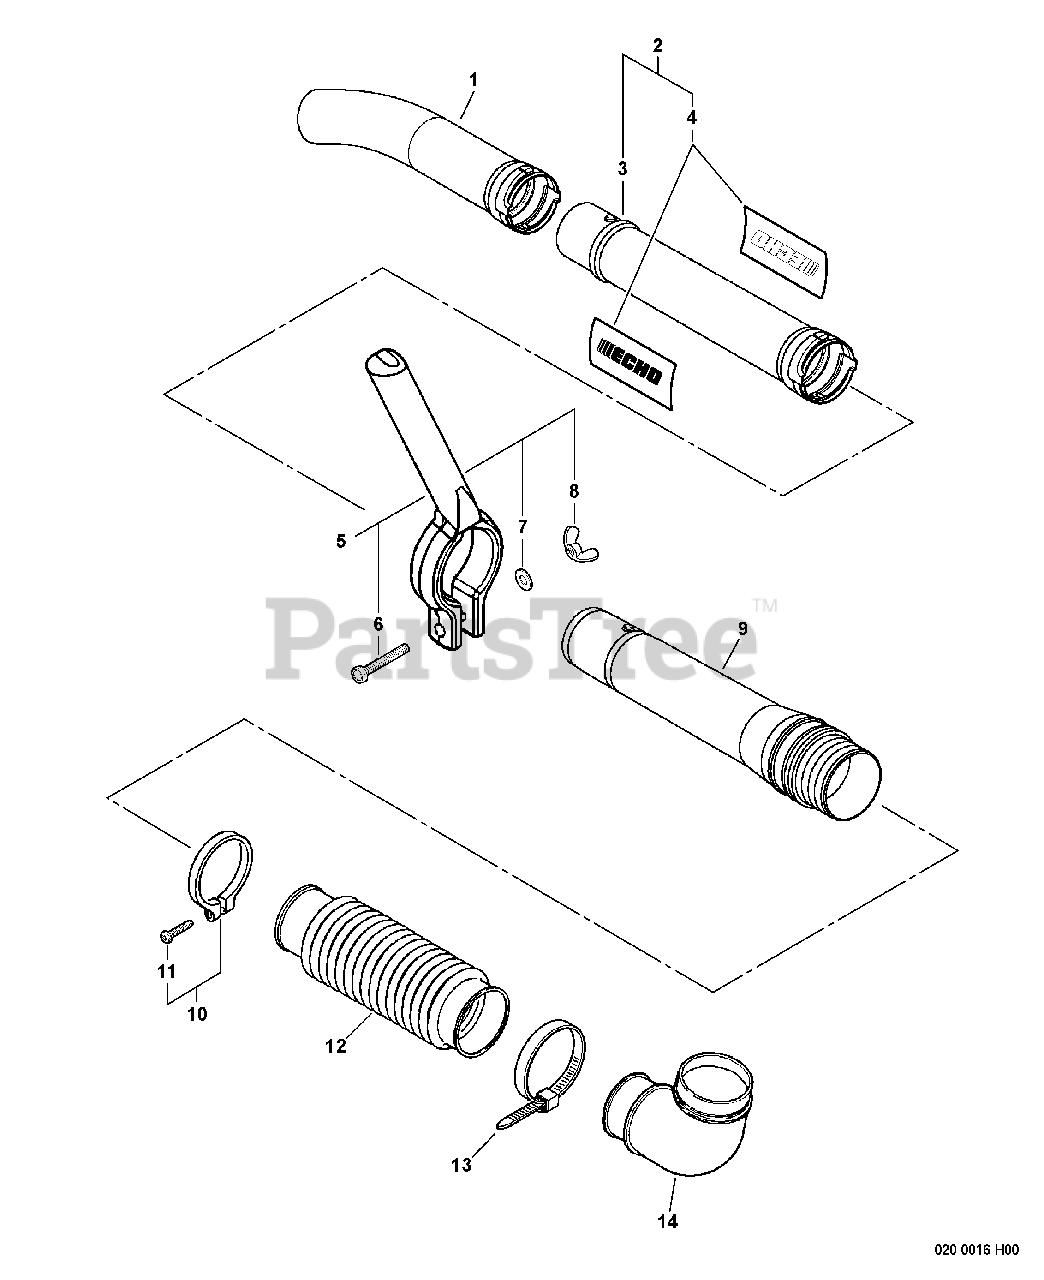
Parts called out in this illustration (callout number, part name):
1	TUBE, BLOWER - CURVED
2	BLOWER TUBE KIT - STRAIGHT
3	TUBE, BLOWER - STRAIGHT
4	LABEL - ECHO
5	HANDLE ASSY
6	BOLT - 6X45
7	WASHER - 6
8	WINGNUT - 6
9	TUBE, BLOWER - SWIVEL
10	CLAMP KIT
11	SCREW - 5X30
12	TUBE, BLOWER - FLEXIBLE
13	CLAMP, HOSE
14	TUBE, BLOWER - ELBOW
